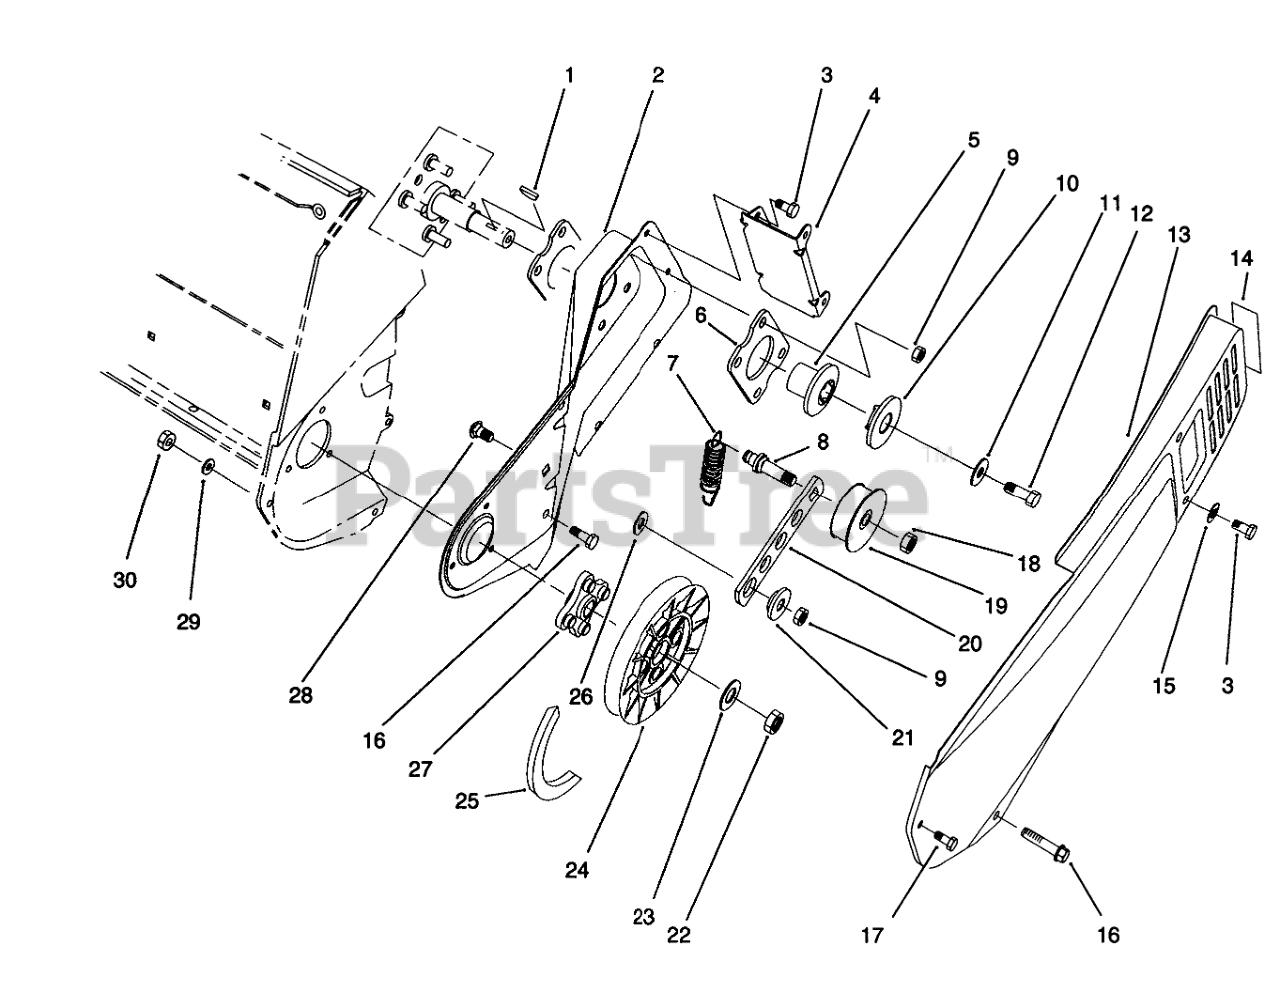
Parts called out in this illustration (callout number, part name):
1	KEY-WOODRUFF
2	Sideplate-LH
3	SCREW-HWH
4	Bracket-Cover
5	Hub-HALF SHEAVE
6	Plate Engine
7	SPRING-EXTENSION
8	PIN-IDLER
9	NUT-LOCK, NI
10	CAP-HALF SHEAVE
11	WASHER-FLAT
12	SCREW-HH
13	Cover-Belt
14	Decal
15	WASHER-FLAT
16	SCREW-PLASTIC
18	NUT-LOCK, NI
19	PULLEY-IDLER
20	ARM-IDLER
21	BUSHING-IDLER
22	NUT-LOCK, NI
23	WASHER-FLAT
24	PULLEY-DRIVEN
25	V-BELT
26	WASHER
28	SCREW-CARR
29	WASHER-FLAT
30	NUT-LOCK, NI
